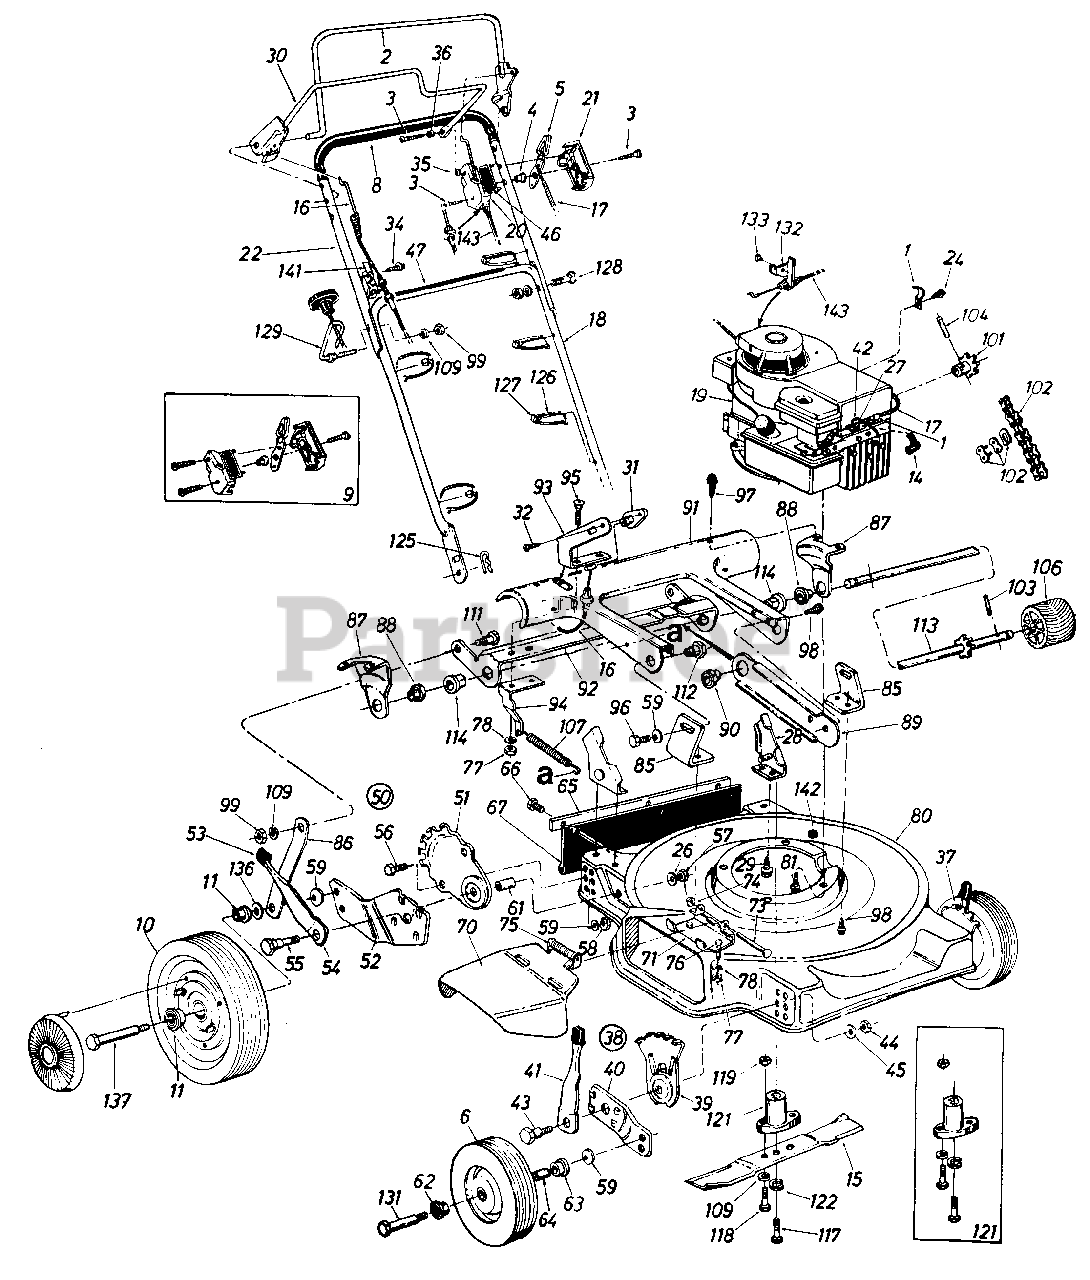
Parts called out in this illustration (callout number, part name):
1	Casing Clamp
2	Control Handle Ass'y. L.H.
3	Truss Mach. Hi-B Tap Scr. #12 x 1.5"
4	Control Disc Pin
5	Throttle Control Lever
6	Front Wheel Ass'y. Comp.
8	Grip
9	Control Housing Comp.
10	Rear Wheel Ass'y. Comp.
11	Fl. Ball Brg. 1/2" I.D.
14	Spark Plug Insulator
15	22" Blade
16	Clutch Cable w/Spring 33"
17	Throttle Wire 53"
18	Lower Handle
19	Engine
20	Clutch Panel Half
21	Control Panel Half
22	Upper Handle (Chrome)
24	Hex B-Tap Scr. #10 x .38"
26	Bell-Wash. 5/16" I.D.
27	Hex "B"-Tap Scr. #10 x .38"
28	Handle Brkt. Ass'y L.H.
29	Hex B-Tap Scr. 5/16-18 x .5"
30	S.P. Bail Ass'y.
31	Barrel Cable Hold-Down R.H.
32	B-Tap Scr. #10 x .38 Lg.
34	Hex Wash. AB-Tap Scr. 5/16 x .75
35	Spr-Wash. .206 I.D. x .448
36	Spacer .23 I.D. x .30 O.D.
37	Front Height Adj. Ass'y. L.H.
38	Front Height Adj. Ass'y. R.H.
39	Height Adj. Plate
40	Pivot Bar
41	Spring Lever Ass'y. w/Knob
42	Casing Clamp
43	Shld. Bolt .50 Dia. x .430
44	Hex Nut 3/8-16 Thd.
45	Bell-Wash. .39 I.D. x 1.38 O.D.
46	Control Label
47	Instruction Label
50	Rear Height Adj. Ass'y. R.H.
51	Index Plate
52	Pivot Bar R.H.
53	Spring Lever Knob
54	Spring Lever
55	Shld. Bolt .50 Dia. x .433
56	Hex Bolt 3/8-16 x .75
57	Hex Cent. L-Nut 5/16-18 Thd.
58	Hex Nut 3/8-16 Thd.
59	Bell-Wash. .40 I.D. x .88 O.D.
61	Spacer .383 I.D. x .503 O.D.
62	Ball Brg. 3/8" I.D.
63	Ball Brg. 1/2" I.D.
64	Spacer
65	Retaining Strip
66	Hex AB-Tap Scr. 1/4 x .62
67	Rear Flap Ass'y.
70	Chute Deflector Ass'y.
71	Adapter Plate
73	Pivot Pin
74	Push Nut 1/4"
75	Torsion Spring
76	Hex Bolt 1/4-20 x .50 Lg.
77	Hex Nut 1/4-20 Thd.
78	L-Wash. 1/4 I.D.
80	22" Deck Ass'y.
81	Hex TT-Tap Scr. 3/8-16 x 1.0
85	Pivot Brkt.
86	Link
87	Axle Brkt.
88	Fl. Ball Brg. 1/2" I.D.
89	Brg. Support
90	Fl. Ball Brg. 1/2" I.D.
91	Pinion-Pivot Cover
92	Drive Engagement Cam
93	Engagement Arm L.H.
94	Spring Bracket
95	Carriage Bolt 1/4-20 x .62
96	Hex Bolt 3/8-16 x .50 Lg.
97	Hex AB-Tap Scr. 1/4 X .62
98	Hex AB-Tap 1/4 X .62"
99	Hex Nut 5/16-18 Thd.
101	1 OT Sprocket Ass'y.
102	#48 Chain 1/2" Pitch 50 Links
103	Spring Pin Spir. 3/16 Dia. x 1 .25
104	Spring Pin Spir. 3/16 Dia. x 1 .0
106	Drive Pinion
107	Extension Spring 4.25 Lg.
109	L-Wash. 5/16 I.D.
111	Shld. Bolt .437 Dia. x .162
112	Shld. Nut .625 Dia. x .165
113	Pinion Shaft w/7T Sprocket
114	Fl. Ball Brg. .501 I.D.
117	Hex Bolt 3/8-24 x 2.25
118	Hex Bolt 5/16-24 x 1.0 Spec.
119	Hex Nut 5/16-24 Thd.
121	Blade Adapter Kit
122	L-Wash. 3/8 I.D. H.D.
125	Intern. Cot. Pin 5/16 Dia.
126	Cable Tie
127	Cable Anchor
128	Curved Carriage Bolt 5/16-18 x 1.38" Lg.
129	Rope Guide Bolt
131	Front Axle Bolt
132	Cable Bracket
133	Pop Rivet .156" Dia. x .379
136	Fl-Wash. .531 I.D. x .93 O.D.
137	Rear Axle Bolt
141	Cable Brkt.
142	Plastic Plug
143	Control Cable 39" (Green)
